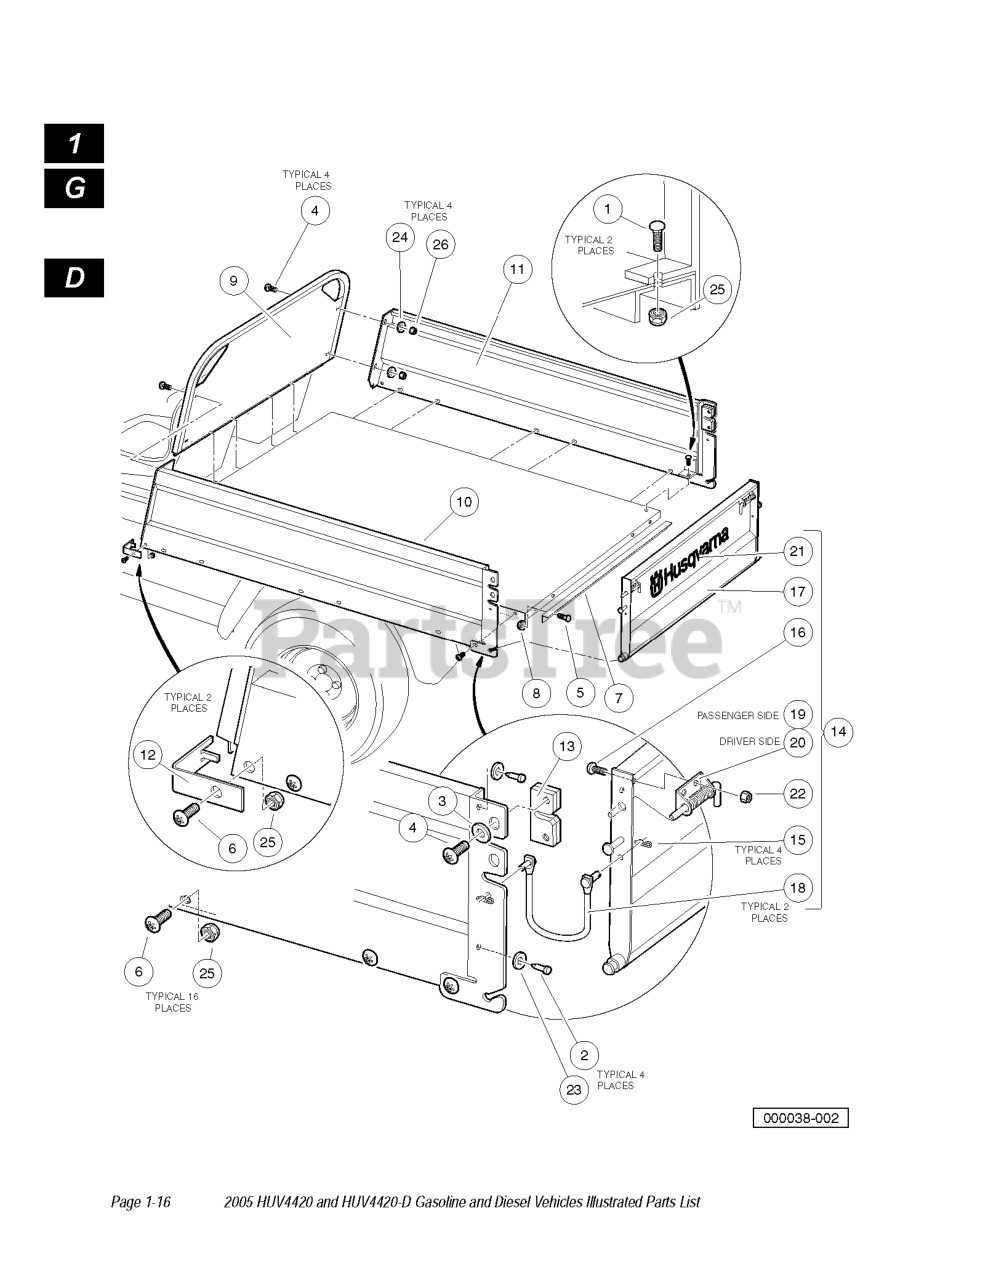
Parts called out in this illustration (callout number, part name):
1	BOLT, 5/16-18 X 1.00 SQ.NECK
2	RUBBER BUMPER
6	SCREW, 5/16-18 X .88 TRX TRUSS
7	BOX BED TAILGATE ANGLE
8	LOCKNUT, 5/16-18 HEX FLANGE
9	FRONT PANEL WELDMENT
10	LEFT PANEL WELDMENT
11	RIGHT PANEL WELDMENT
12	FRONT CORNER CAP
13	SLAM LATCH
14	ASM, TAILGATE, OEM
15	HAIR PIN CLIP
18	TETHER ASSEMBLY
19	SPRING LATCH RIGHT
20	SPRING LATCH LEFT
21	DECAL, TAILGATE,OEM
22	LOCKNUT, 1/4-20 NYLON INSERT
23	WASHER, RUBBER 3/8
24	WASHER 1/4 FLAT
25	LOCKNUT, 5/16-18 NYLON INSERT
26	LOCKNUT, 1/4-20 NYLON INSERT
